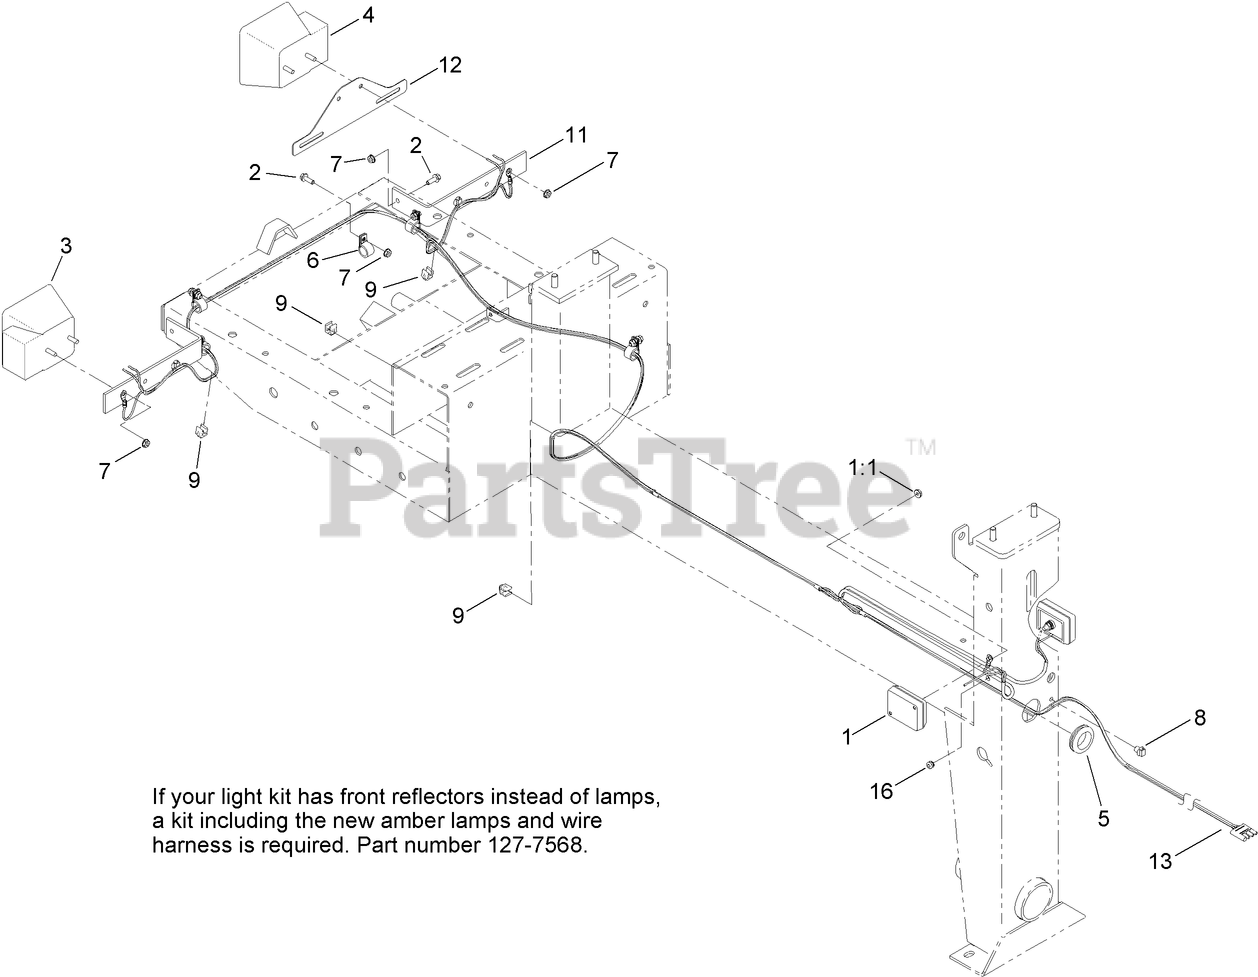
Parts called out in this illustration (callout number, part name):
1	LAMP-MARKER, FRONT SIDE
1:1	NUT-KEPS
2	SCREW-HHF
3	LIGHT-TAIL, RH
4	LIGHT-TAIL, LH
5	GROMMET
6	CLAMP-CABLE
7	NUT-KEPS
8	CLIP-TIE
9	CLIP-EDGE
10	CLIP-EDGE W/TIE, PERPENDICULAR
11	BRACKET-UNIVERSAL
12	HOLDER-PLATE, LICENSE
13	HARNESS-WIRE
16	GROMMET
